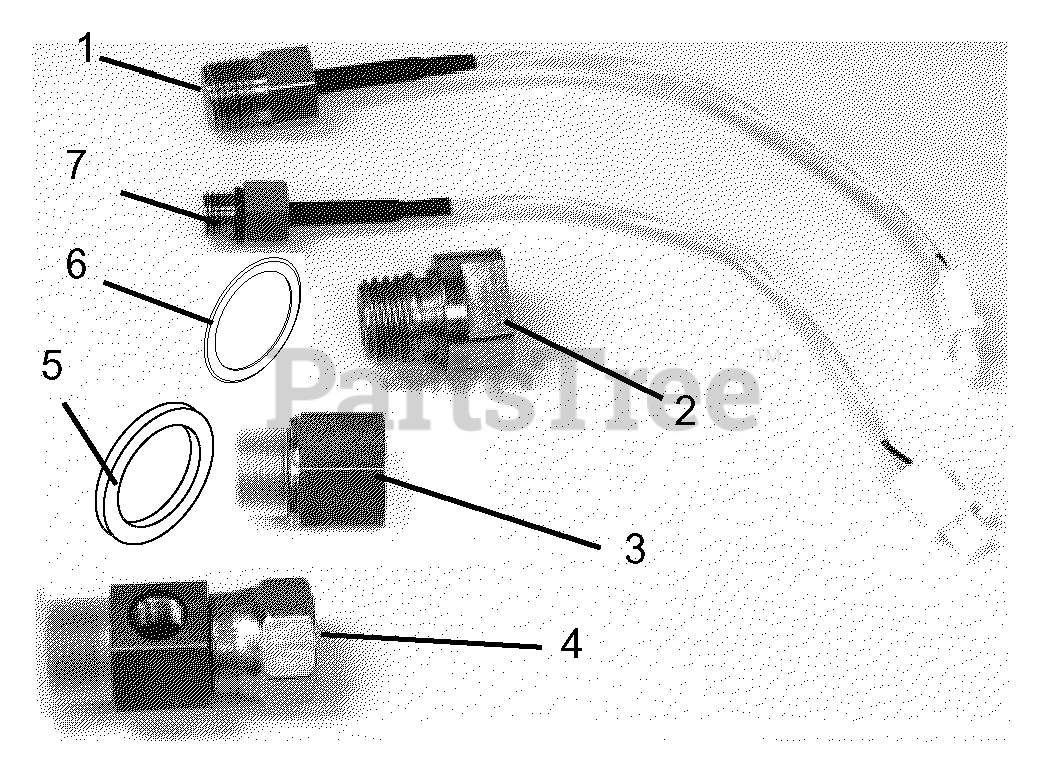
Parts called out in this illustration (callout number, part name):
1	ASSY,SENSOR HARNESS (.375 NPT)
2	ADAPTER,M20M-.375F,59071-7004
3	ADAPTER,M16M-.375F /NPT
4	FTG,HYD.SENSOR TEE 8-4 ORFS
5	SEAL, WASHER (OIL DRAIN PLUG)
6	O-RING KAW #67OD2016
7	ASSY,SENSOR HARNESS (.44UNF)
